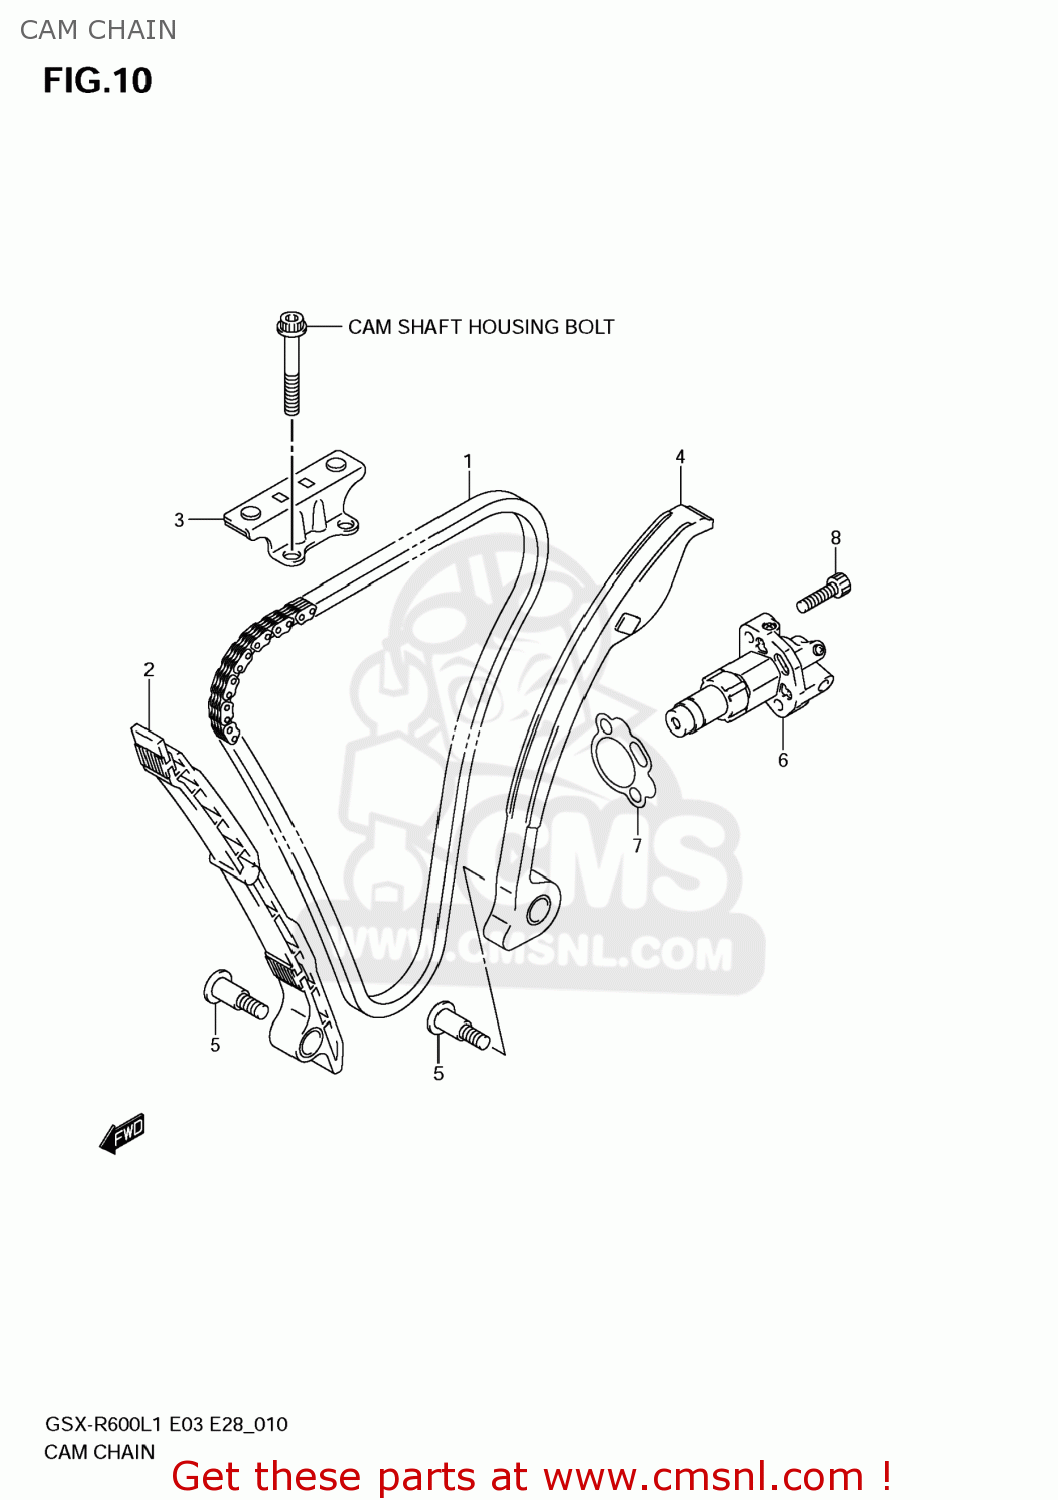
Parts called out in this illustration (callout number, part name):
1	CHAIN,CAMSHAFT DRIVE
2	GUIDE,CAM CHAIN NO.1
3	GUIDE,CAM CHAIN NO.2
4	TENSIONER,CAM CHAIN
5	BOLT,CAM CHAIN TENSIONER
6	ADJUSTER ASSY,TENSIONER
7	GASKET,TENSIONER ADJUSTER (NAS)
8	BOLT
